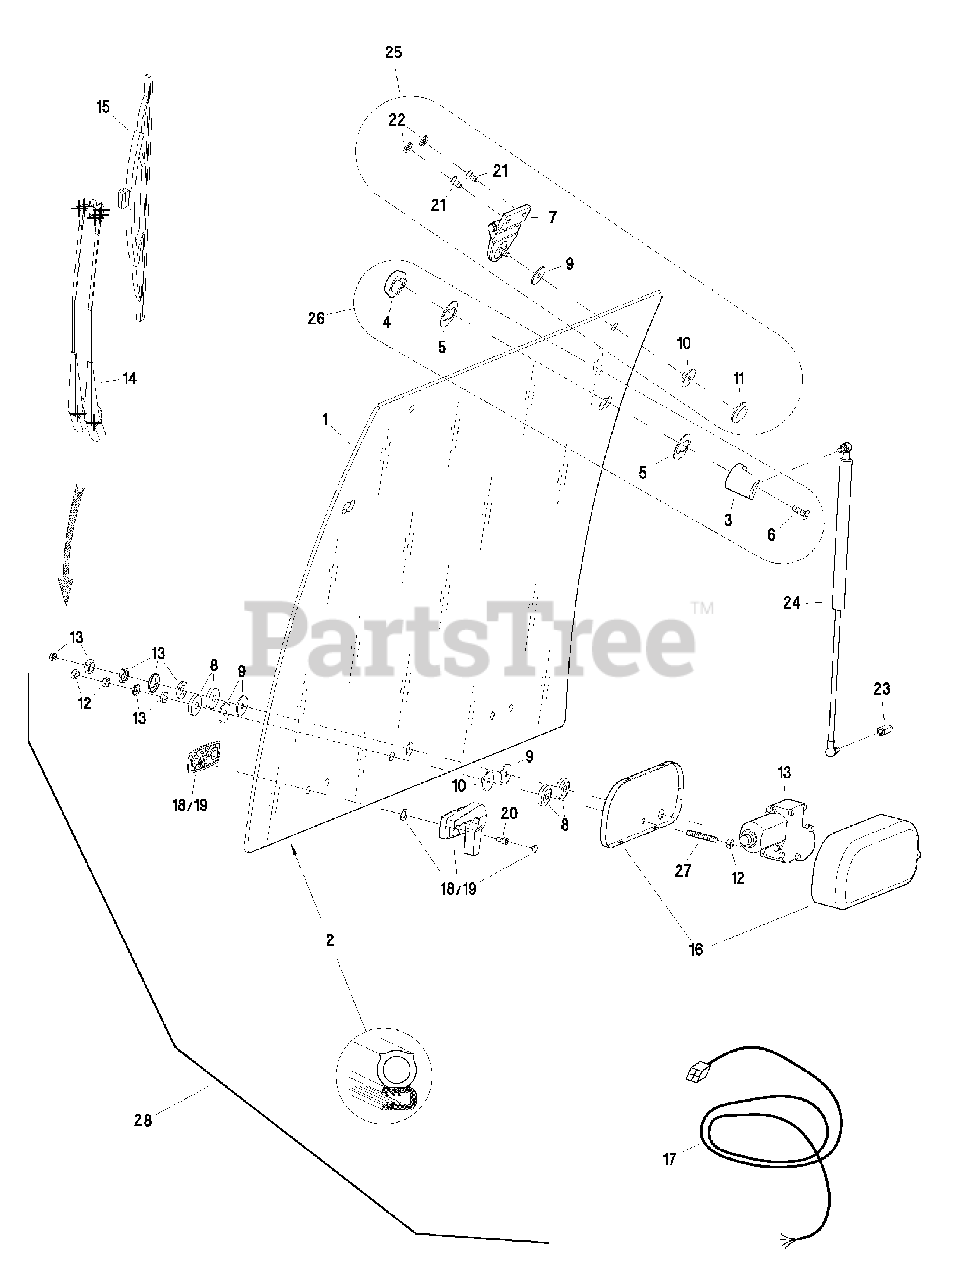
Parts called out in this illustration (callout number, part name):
1	Glass WS
2	Sealing tube profile
3	Pneumatic spring mounting inside
4	Pneumatic spring mounting outside
5	Rubber washer
7	PVC hinge complete
9	Rubber washer
10	Rubber washer with neck
11	PA - disk M8
13	Wiper motor 85 degrees / 12V
14	Wiper arm 400-500mm lg.
15	Wiper blade 450mm lg.
16	Cover wiper motor
17	Cable harness wiper motor
18	Locking device handle left
19	Locking device handle right
22	Cover cap countersunk head screw
23	Pneumatic spring sleeve l=22mm 2x M8
24	Pneumatic spring 320mm 150N
25	Set of hinges
26	Set of pneumatic spring mounting
27	M8 threaded rod l=75mm
28	Windshield complete (Includes all ref. nos. except ref. nos. 21 & 22)
